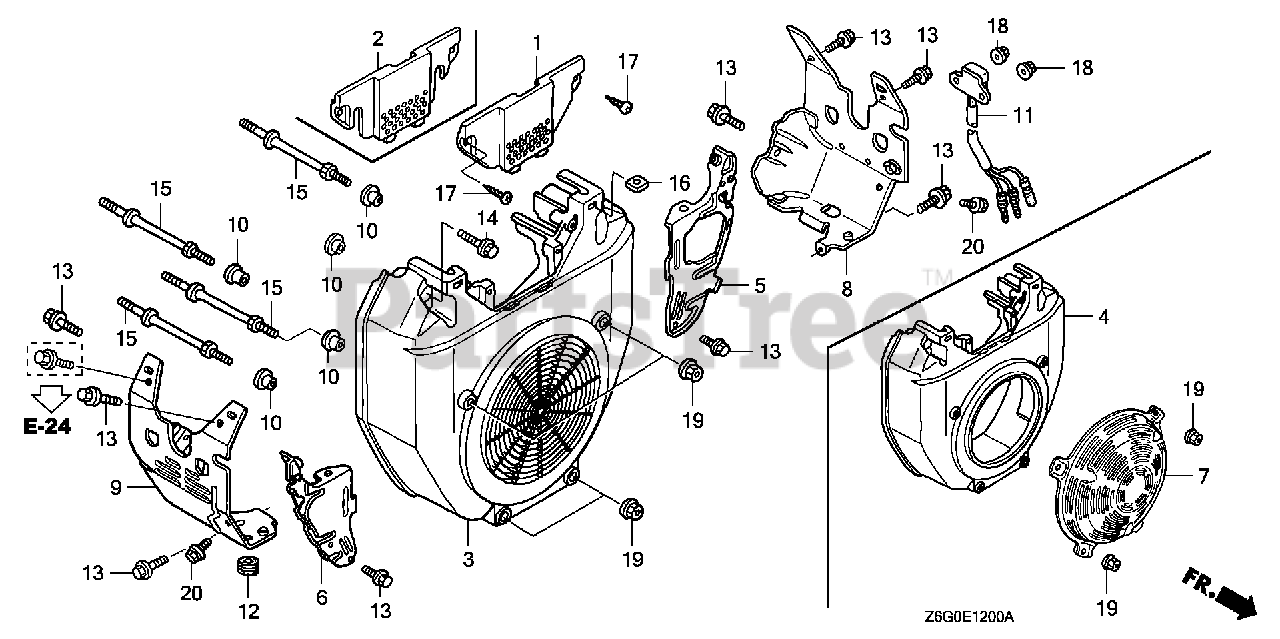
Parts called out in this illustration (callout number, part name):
1	COVER, FUEL PUMP
3	COVER, FAN *NH1* (BLACK)
3	COVER, FAN *R280* (POWER RED)
5	PLATE, SIDE
6	PLATE, SIDE (R. SIDE)
8	SHROUD, R.
9	SHROUD (R. SIDE)
10	COLLAR B, TAILLIGHT
12	RUBBER, RR. FENDER CUSHION
13	BOLT, FLANGE (6X12) (CT200)
14	BOLT, FLANGE (6X23)
15	BOLT, STUD (6X71)
16	NUT, SQUARE (5MM)
17	SCREW, TAPPING (5X20)
19	NUT, FLANGE (6MM)
20	BOLT, FLANGE (6X8)
